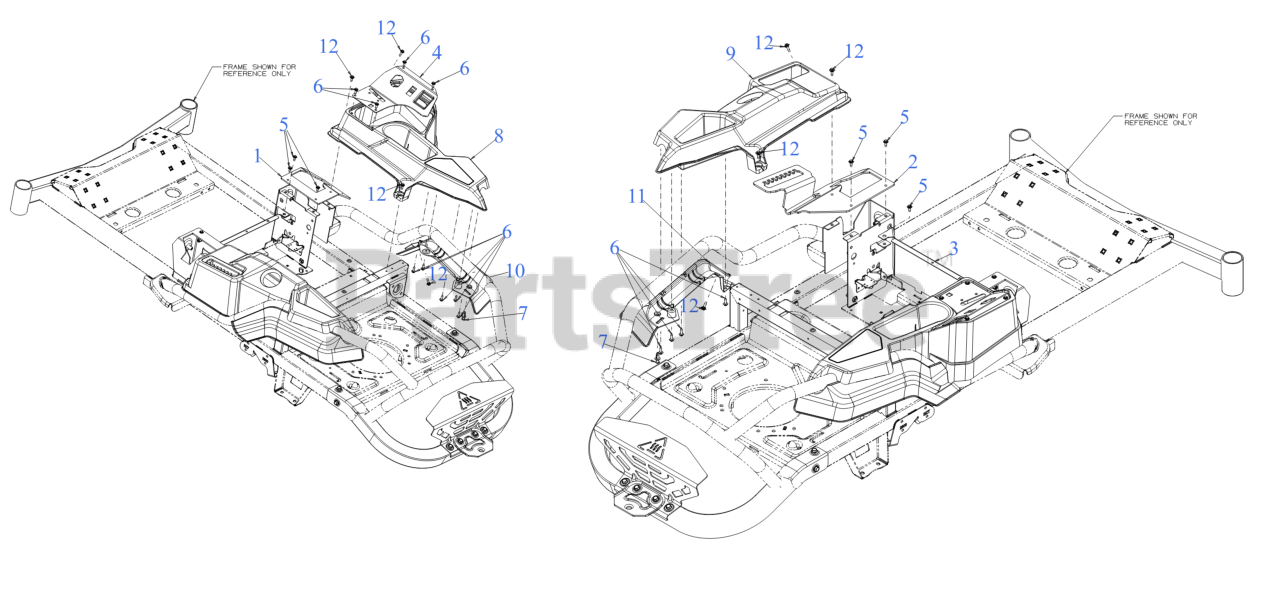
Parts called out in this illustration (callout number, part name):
1	CONTROL BRACKET (RH)
2	HEIGHT INDEX BRACKET (LH)
3	SEAT BOX FRONT PLATE
4	CONSOLE COVER (RH)
5	SCREW M6-1 x .625
6	SCREW 1/4-10 x .750
7	PLASTIC RIVET
8	CONSOLE (RH)
9	CONSOLE (LH)
10	FENDER CONSOLE (RH)
11	FENDER CONSOLE (LH)
12	SHOULDER SCREW M6-1 .368 X.115
